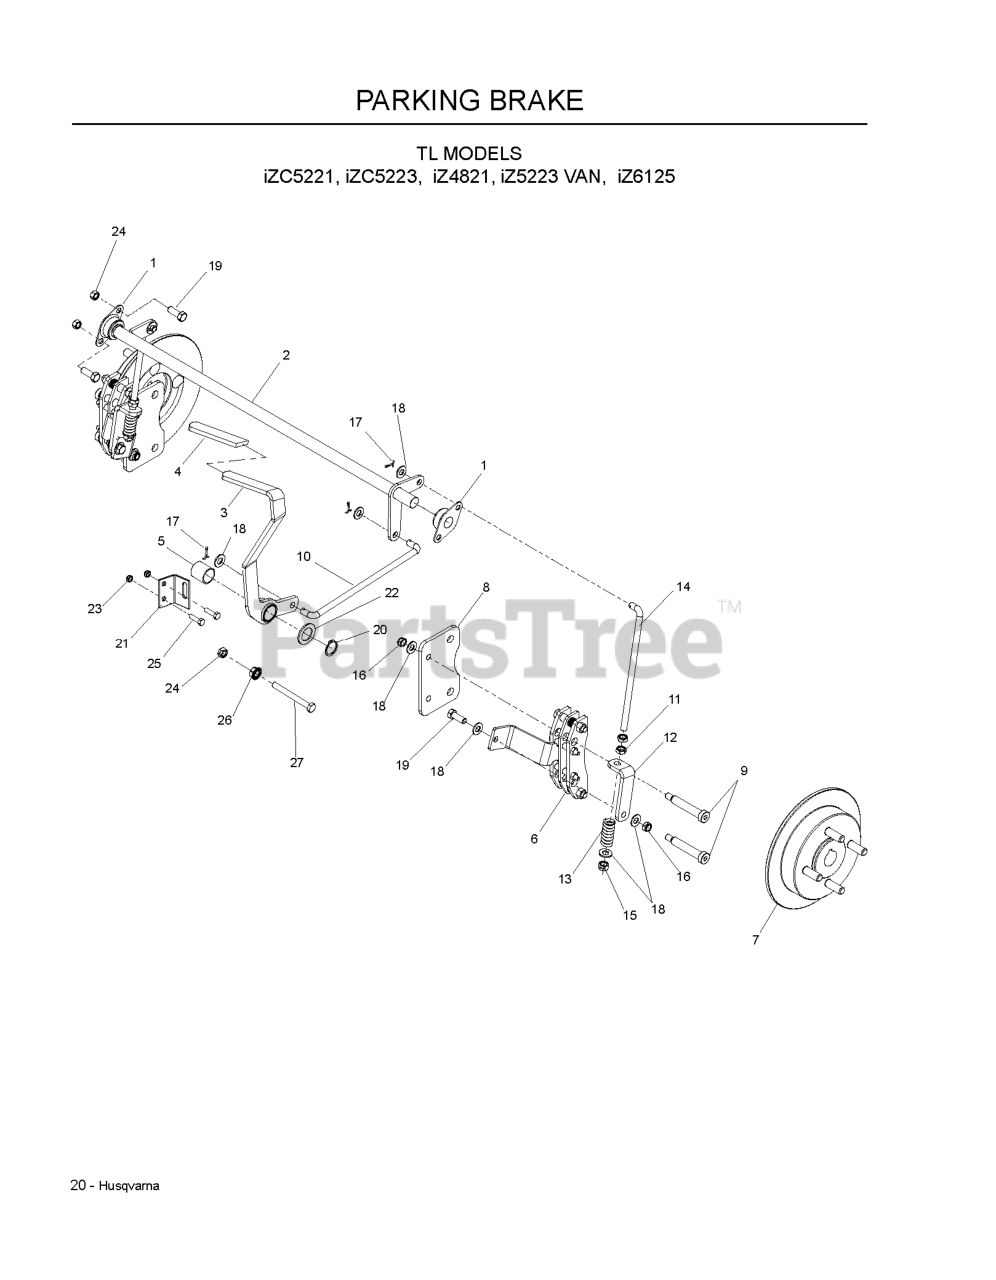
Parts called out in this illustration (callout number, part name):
1	FLANGE BEARING
2	BRAKE CROSS SHAFT
3	BRAKE LEVER WLDMT
4	GRIP, PARK BRAKE
8	PLATE, BRAKE
9	SB 3/8-16 X 2-1-1/2 SKT HDD ZD
10	LINKAGE, BRAKE
11	NUT 3/8-24 JAM
12	BRACKET, L
14	LINKAGE, REAR BRAKE
15	NUT 3/8F CENTERLOCK
16	NUT HEX 3/8-16 NYLON, THIN
17	COTTER PIN 3/32 X 3/4
18	WASHER 3/8 SAE FLAT
19	HCS 3/8-16X1.GRD.5.ZD
20	RETAINING RING, 7/8"
21	BRACKET, BRAKE SWITCH
22	BSHG .875 X 1.375 X .074 ZD
23	NUT.1/4-20.HEX.NYLOC.ZD
24	NUT 3/8-16 NYLOC
25	HCS 1/4C X 3/4 HCS
26	NUT 3/8C WHIZ
27	HCS 3/8C X 2 1/2
